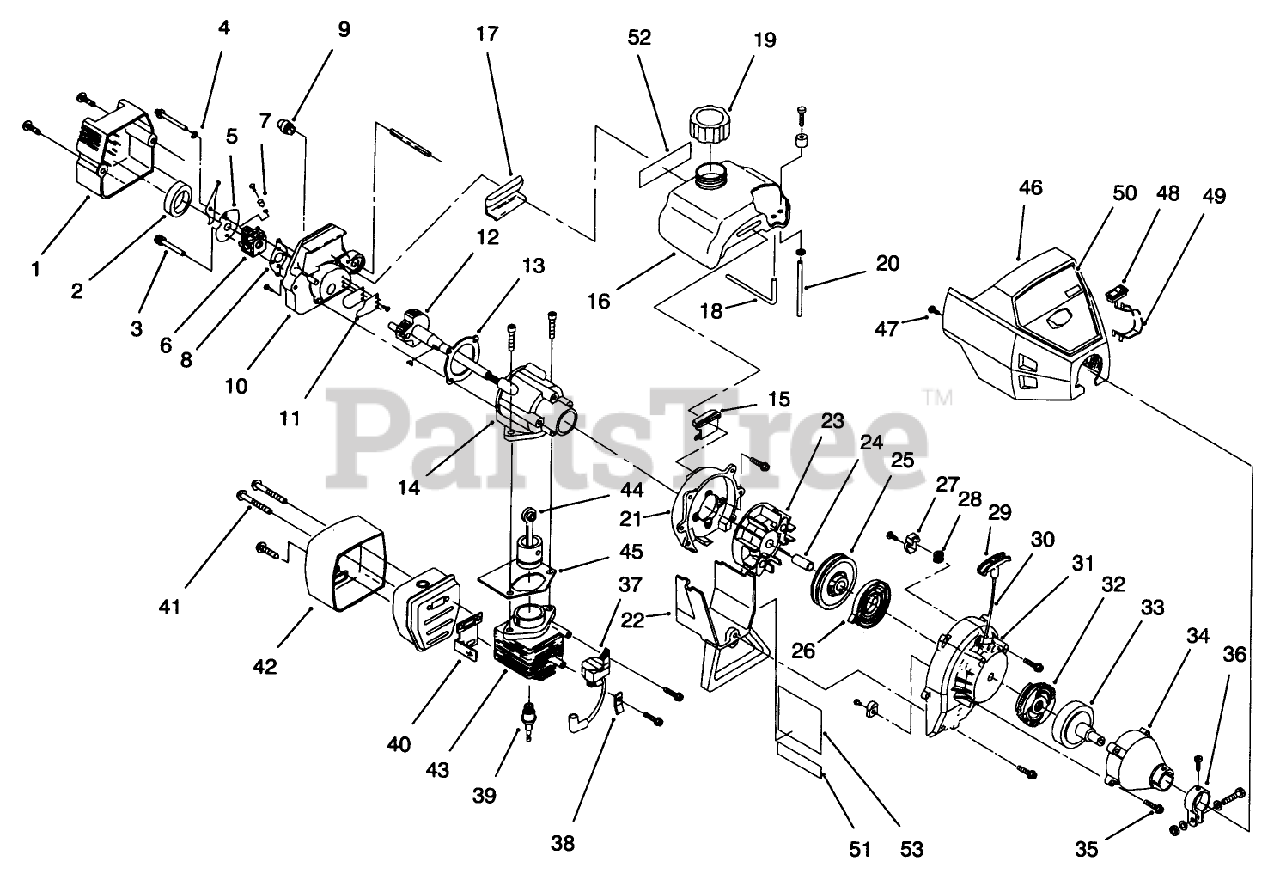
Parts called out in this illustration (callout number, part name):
1	Carburetor/Air Cleaner Asm. (Incl. Ref. #2)
2	FILTER - AIR CLEANER
3	ASSEMBLY - MOUNTING BOLT
4	WASHER - WAVEY
5	LEVER - CHOKE & PLATE
6	Carburetor Asm.
7	THROTTLE ADJ ASM
7	ASM - THROTTLE ADJUSTMENT
8	CARBURETOR GASKET(10 PER PACK)
9	PRIMER & HOSE ASM
10	Carburetor Mount Asm.
11	ASSEMBLY - REED
12	ASM - POWER SHAFT
13	CARB MT GASKET (10-PK)
14	Crankcase Service Asm. (Incl. Ref. #12)
15	FRONT MOUNTING PAD
16	Fuel Tank Asm. (Incl. Ref. #18-20)
17	REAR MOUNTING PAD
18	ASSEMBLY - RETURN LINE
19	FUEL TANK CAP
20	FUEL LINE ASM
21	SHROUD ASM
22	Shroud Extension & Stand
23	FLYWHEEL
24	SPACER
25	RECOIL PULLEY ASM
26	RECOIL SPRING
27	PULLEY RETAINER ASM
28	ROPE GUIDE
29	Handle-Pull
31	ASSEMBLY - STARTER HSG
32	Clutch Rotor Asm.
33	CLUTCH DRUM ASM
34	Clutch Cover Asm.
35	CLUTCH COVER SCREW ASM
36	CLAMP ASM - UPPER
37	Module Asm.
38	GROUND TAB
39	SPARK PLUG
40	GASKET - EXHAUST
41	ASM - MUFFLER MTG BOLT
42	Muffler Asm. (Incl. Ref. #41)
43	ASSEMBLY - CYLINDER
44	PISTON & ROD ASM
45	CYLINDER GASKET
46	COVER - ENGINE
47	Screw
48	SWITCH ASM
49	LEAD WIRE ASM
50	DECAL - TORO
51	Decal-Warning
52	Decal-Fuel & Oil Mix
52	DECAL - CARBURETOR
